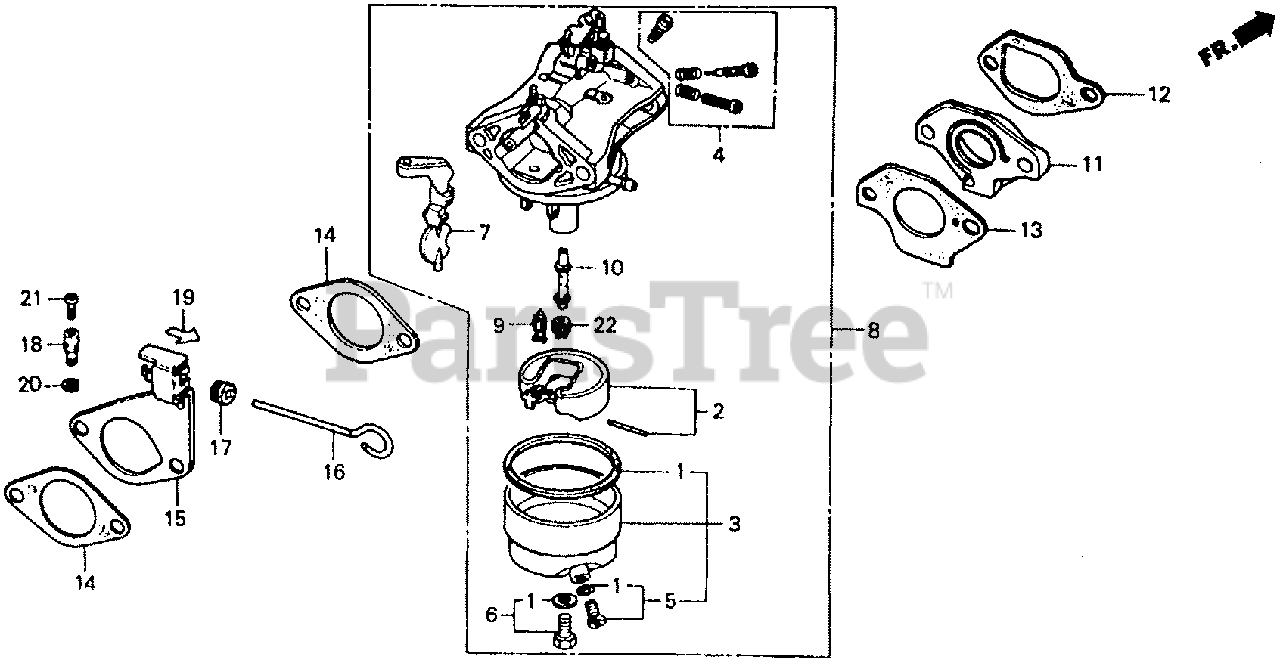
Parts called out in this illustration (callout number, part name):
1	GASKET SET
2	FLOAT SET
3	CHAMBER SET, FLOAT
4	SCREW SET A
5	SCREW SET, DRAIN
6	SCREW SET B
7	CHOKE SET
8	CARBURETOR ASSY. (BB33C D)
9	VALVE, FLOAT
10	NOZZLE, MAIN
11	INSULATOR, CARBURETOR
12	GASKET, INSULATOR
13	GASKET, CARBURETOR
14	GASKET, AIR CLEANER
15	STAY, CHOKE CONTROL
16	ROD, CHOKE CONTROL
17	GROMMET, CHOKE ROD
18	HOLDER, CABLE
19	MARK, CHOKE
20	CIRCLIP (5MM)
21	SCREW, PAN (4X8)
22	JET, MAIN (#75)
22	JET, MAIN (#78)
22	JET, MAIN (#80)
22	JET, MAIN (#82)
22	JET, MAIN (#85)
